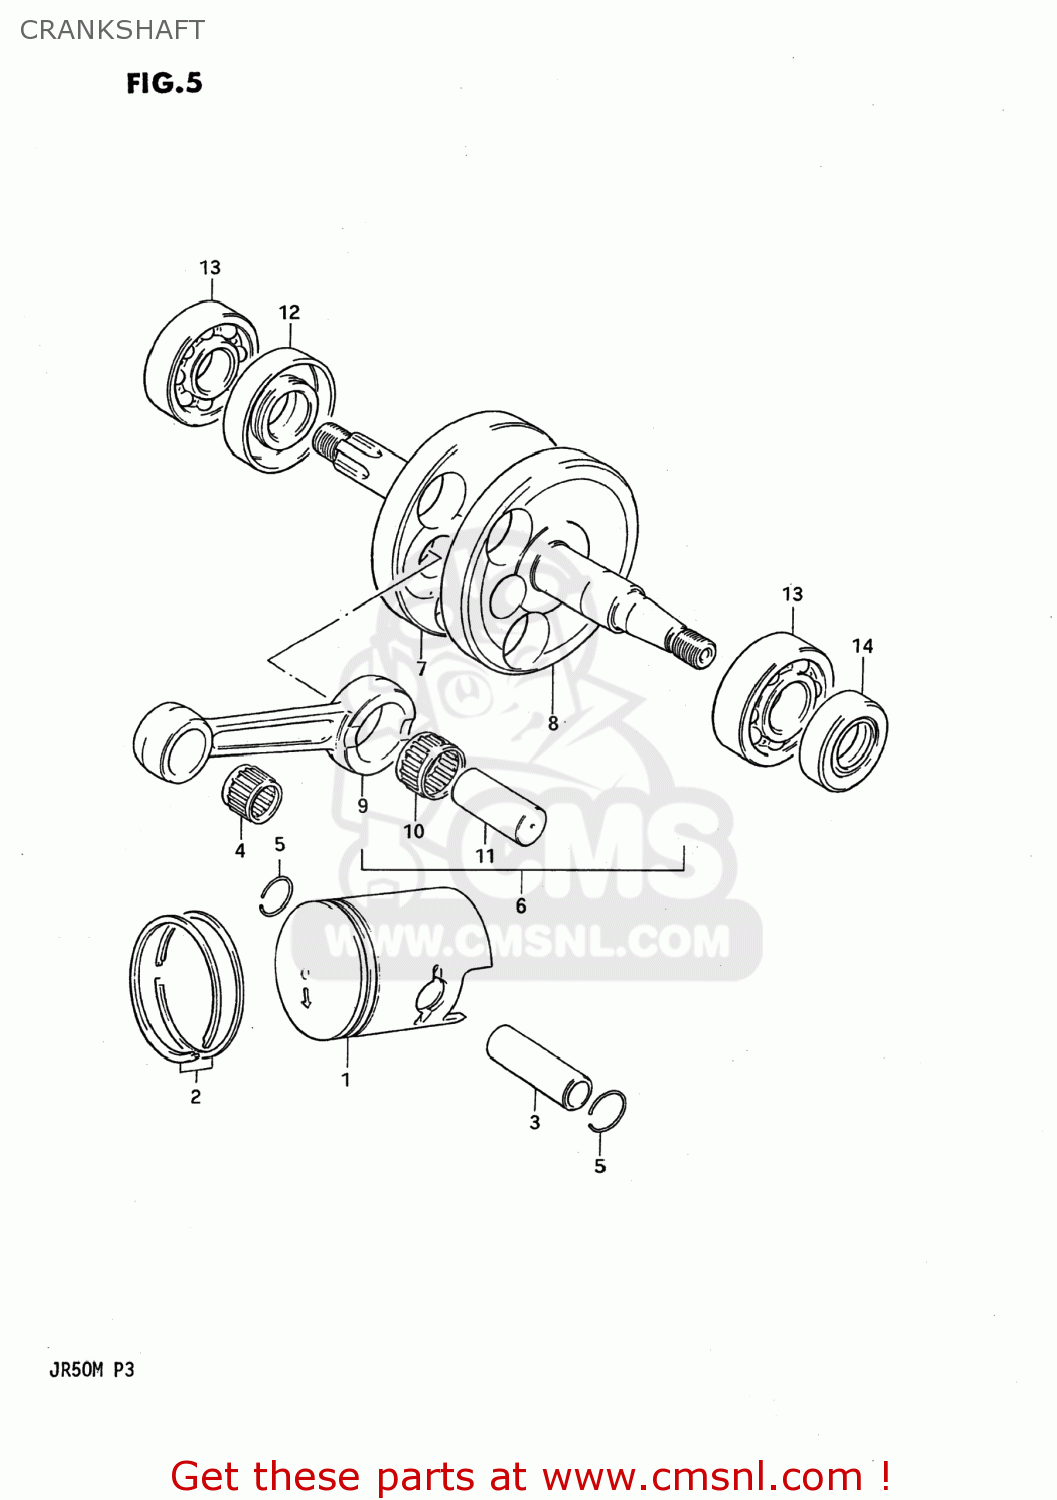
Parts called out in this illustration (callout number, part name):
1	PISTON
2	RING SET,PISTON
3	PIN,PISTON
4	ROLLER BEARING (12X16X1
5	RING,SNAP
6	CRANKSHAFT ASSY
7	CRANKSHAFT,R
8	CRANKSHAFT,L
9	ROD,CONNECTING
10	BEARING(15X21X9.8)
11	PIN,CRANK
12	SEAL,OIL(22X40X8)
13	BEARING(17X40X12)
14	OIL SEAL (17X29X7)
